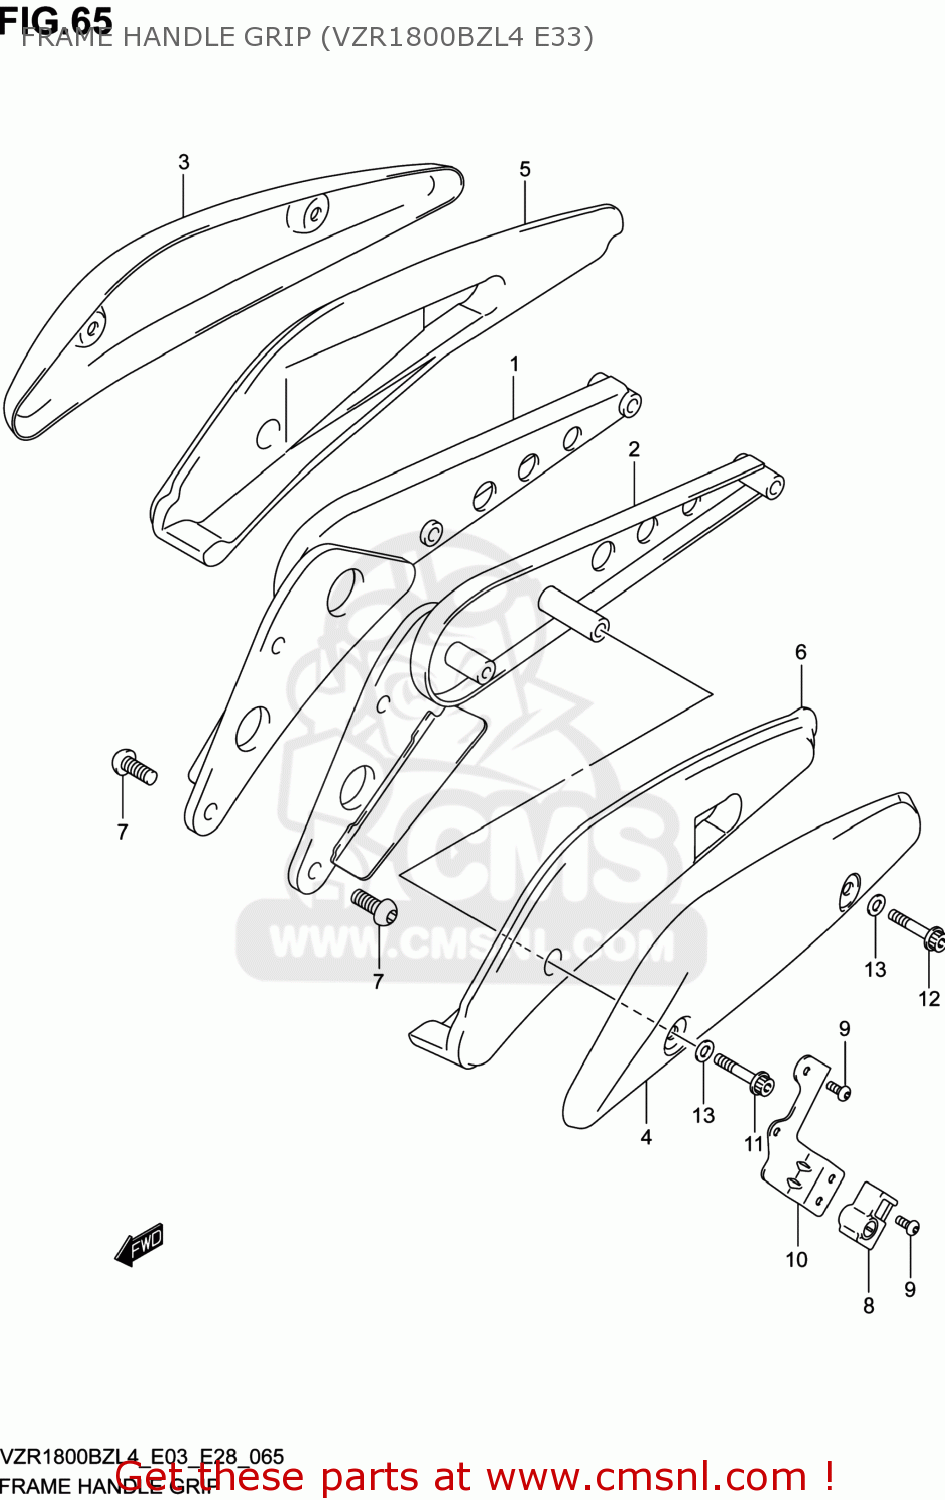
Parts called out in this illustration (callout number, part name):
1	GRIP,FRAME HANDLE,R
2	GRIP,FRAME HANDLE,L
3	PLATE,FRAME HANDLE,R
4	PLATE,FRAME HANDLE,L
5	RUBBER,FRAME HANDLE GRIP,R
6	RUBBER,FRAME HANDLE GRIP,L
7	BOLT(10X25)
8	LOCK SET,HELMET
9	SCREW(6X14)
10	BRACKET,HELMET LOCK
11	BOLT(8X70)
12	BOLT(8X50)
13	WASHER
